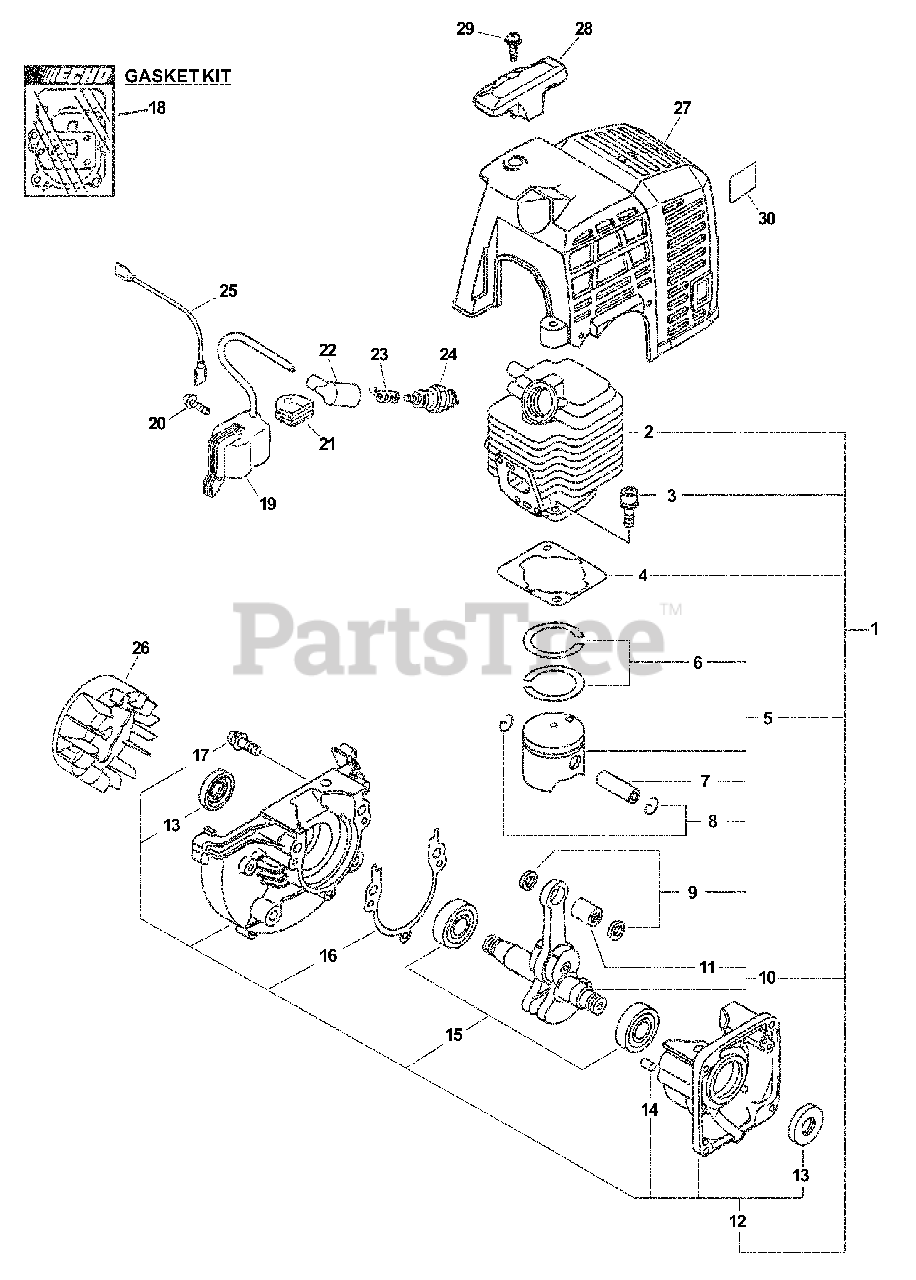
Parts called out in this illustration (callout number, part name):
1	SHORT BLOCK -- SB1026
2	CYLINDER
3	SCREW - 5X22
4	GASKET, CYLINDER
5	PISTON KIT
6	RING, PISTON
7	PIN, PISTON
8	RING, RETAINING
9	SPACER, PISTON
10	CRANKSHAFT ASSY
11	BEARING, NEEDLE
12	CRANKCASE KIT
13	SEAL, OIL
14	PIN - LOCATING
15	BEARING, BALL - 6201
16	GASKET, CRANKCASE
17	SCREW - 5X28
18	GASKET KIT
19	COIL, IGNITION
20	SCREW - 4X22
22	CAP, SPARK PLUG
23	TERMINAL, SPARK PLUG CAP
24	SPARK PLUG -- BPM-7A
24	SPARK PLUG -- RCJ-7Y
25	LEAD - IGNITION
26	FLYWHEEL
27	COVER, ENGINE
28	GUARD - TOP
29	SCREW - 5X16
30	LABEL - HOT SURFACE
